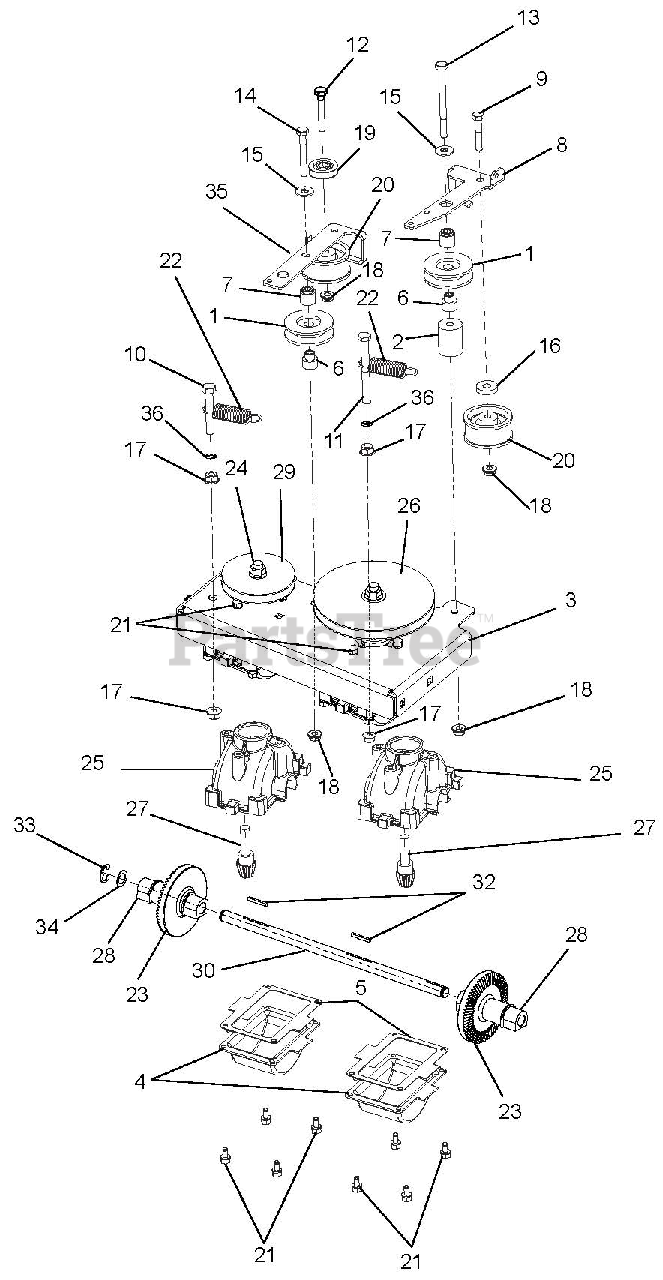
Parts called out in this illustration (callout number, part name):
1	IDLER, 3L FRONT SIDE .38X1.875
2	SPACER, REVERSE IDLER
3	PLATE, WAW TRANSMISSION MOUNT
4	SUMP, GEARBOX
5	GASKET, TRANSMISSION
6	SPACER, V-IDLER PULLEY
7	SPACER, IDLER ARM
8	BRKT-TRANS IDLER ARM
9	@BLT-HEX .25-20X1.50 GR5 YWZC
10	@BLT-HEX .31-18X2.00 GR5 YWZC
11	@BLT-HEX .31-18X3.50 GR5 YWZC
12	@BLT-HEX .25-20X1.75 GR5 YWZC
13	@BLT-HEX .25-20X3.25 YWZC
14	@BLT-HEX .25-20X2.00 GR5 YWZC
15	@WSHR-FL-STL.312X.734X.065 YWZ
16	WSHR-FL-STL .328X.87X.179 YWZC
17	@NUT-SPNLK-FLG .312-18 YWZC
18	@NUT-LK-TOP-FLG .25-20 YWZC
19	PULLEY, CABLE
20	PULLEY, ILDER .25X1.875X.97
21	SCR-TAP 10-24X.375 PRE-COAT 80
22	SPRG, TENSION .063X.625X2.50
23	GEAR, BEVEL (CU INFL, KEYWAY)
24	@NUT-LK-TOP-FLG .38-16 YWZC
25	HOUSING, WBLM GEAR BOX
26	PULLEY, WAW REVERSE INPUT
27	PINION, GEARBOX INPUT
28	BUSHING, TRANS OUTPUT SHAFT
29	PULLEY, WAW INPUT
30	SHAFT-TRANS OUTPUT
32	KEY, 1/8 X 1/8 X 1.0
33	RG-RTNG-EXT .500X.042 (E)
34	WASHER, .500X.750X.020 THRUST
35	ARM, WAW FORWARD IDLER (3 MPH)
36	NUT-PUSH .312
